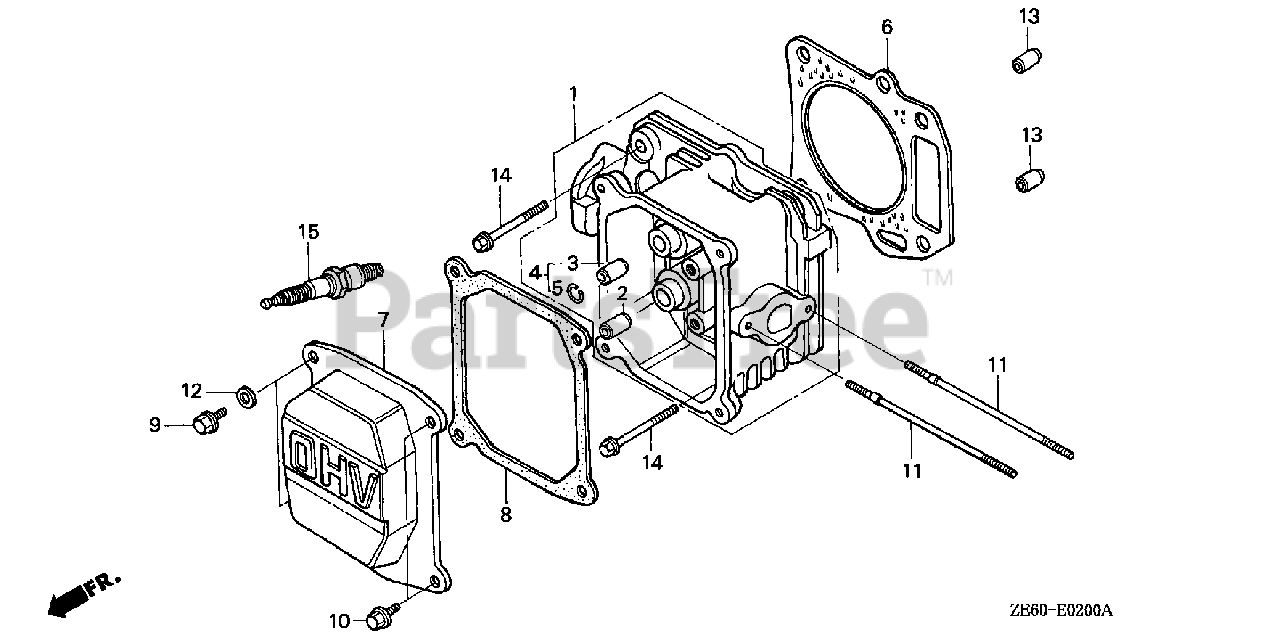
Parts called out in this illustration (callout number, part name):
1	CYLINDER HEAD (USA)
1	CYLINDER HEAD
2	GUIDE, VALVE (OVER SIZE)
4	GUIDE, EX. VALVE (OVER SIZE)
5	CLIP, VALVE GUIDE
6	GASKET, CYLINDER HEAD
7	COVER, HEAD
8	GASKET, HEAD COVER
9	BOLT, FLANGE (6X13)
10	BOLT, FLANGE (6X14)
11	BOLT, STUD (6X97)
12	WASHER (6X17)
13	PIN, DOWEL (10X16)
14	BOLT, FLANGE (8X50)
15	SPARK PLUG (BPR4ES) (NGK)
15	SPARK PLUG (W14EPR-U) (DENSO)
15	SPARK PLUG (BPR5ES) (NGK)
15	SPARK PLUG (W16EPR-U) (DENSO)
15	SPARK PLUG (BPR6ES) (NGK)
15	SPARK PLUG (W20EPR-U) (DENSO)
